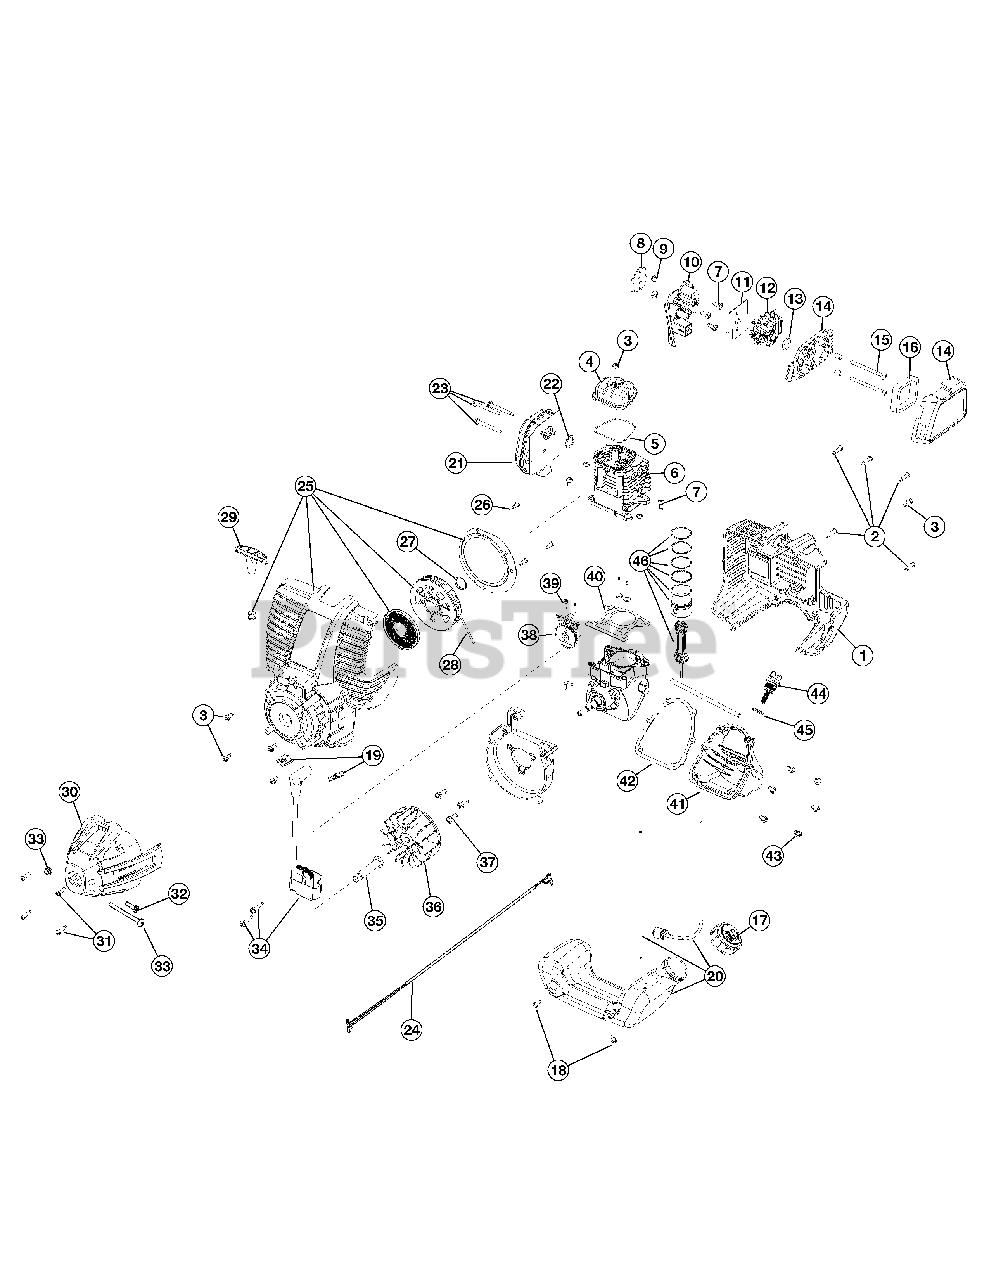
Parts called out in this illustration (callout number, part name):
1	Engine Cover
3	Screw
4	Valve Cover
5	Valve Cover Gasket
6	Cylinder Assembly
7	Cylinder Screw
8	Insulator Gasket
9	Nut
10	Insulator
11	Carburetor Gasket
12	Carburetor w/Primer
13	Carburetor O-Ring
14	Air Filter Cover Assembly
15	Air Filter Mounting Screw
16	Air Filter
20	Fuel Tank Assembly
21	Muffler Assembly
22	Muffler Gasket
23	Muffler Mounting Screw
25	Starter Housing Assembly
26	Plate Screw
27	Push Nut
29	Pull Handle
30	Clutch Cover Assembly
31	Cover Screw
32	Anti-Rotation Screw
33	Clamping Screw Assembly
34	Ignition Module Assembly
35	Square Nut Drive
37	Shroud Screw
38	Cam Bracket Assembly
39	Cam Bracket Screw
40	Cylinder Gasket
41	Oil Pan
42	Oil Pan Gasket
43	Oil Pan Screw
44	Dipstick Assembly
46	Piston Assembly
